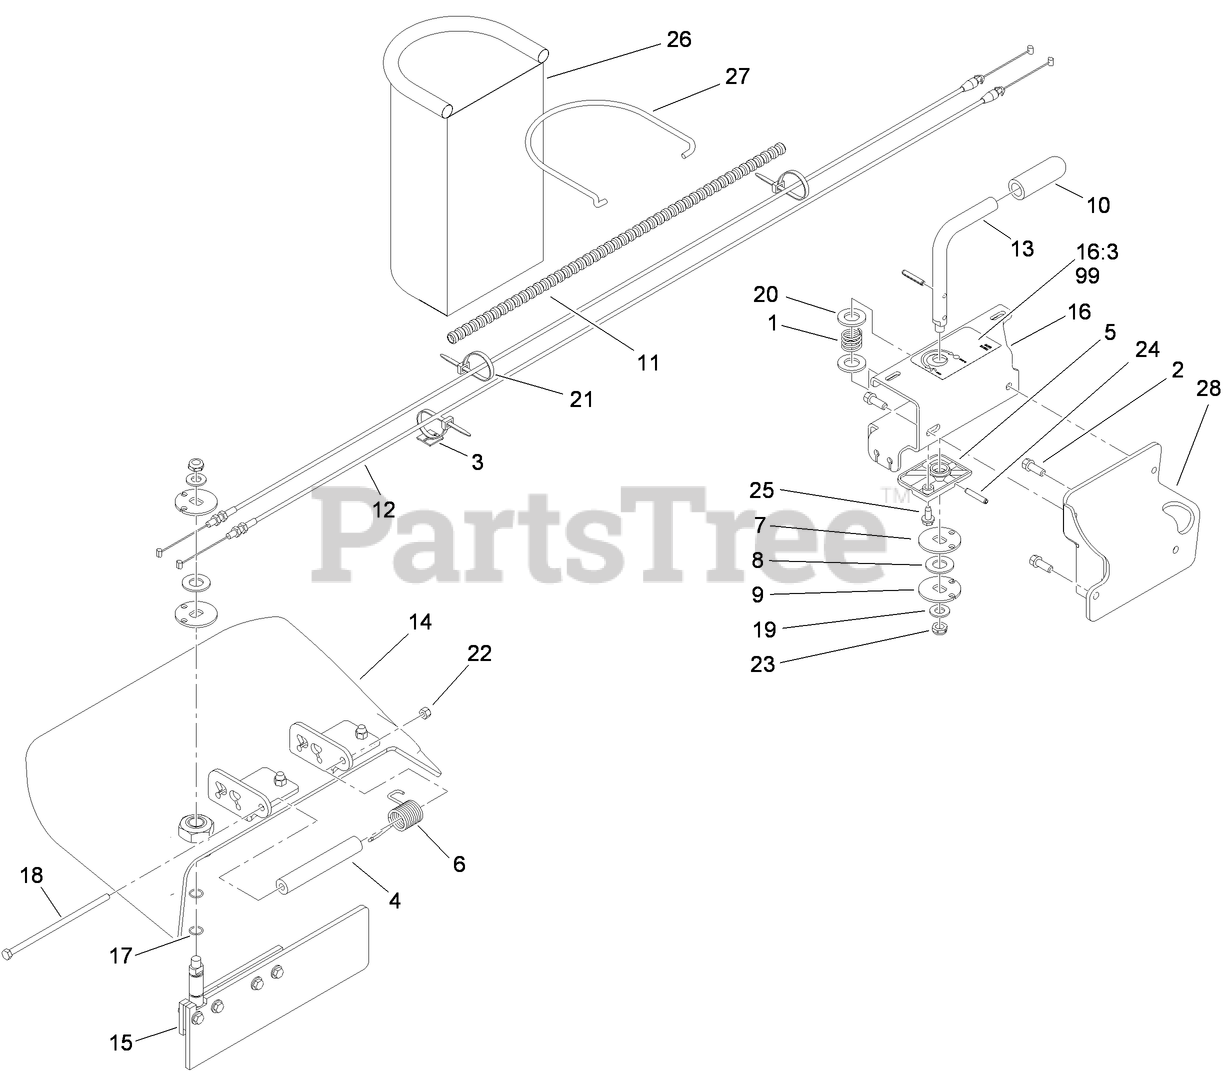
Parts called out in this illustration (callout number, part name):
1	SPRING-COMPRESSION
2	SCREW-HWH
3	MOUNT-TIE, CABLE
4	SPACER
5	BLOCK-DETENT
6	SPRING-TORSION
7	PULLEY-BOTTOM
8	PULLEY-MIDDLE
9	PULLEY-TOP
11	TUBE-CONVOLUTED
13	HANDLE
14	RUBBER DEFLECTOR ASM
15	DOOR ASM
16	CONTROL BRACKET WITH DECAL ASM
16:3	DECAL-GATE, CHUTE
17	O-RING
18	SCREW-HH
19	WASHER-FLAT
20	WASHER-FLAT
21	TIE-CABLE
22	NUT-LOCK, NI
23	NUT-LOCK, NI
24	PIN-ROLL
25	SCREW-HWHTF
26	BAG-TRASH
27	ROD-BAG, TRASH
99	DECAL-GATE, CHUTE (CE)
